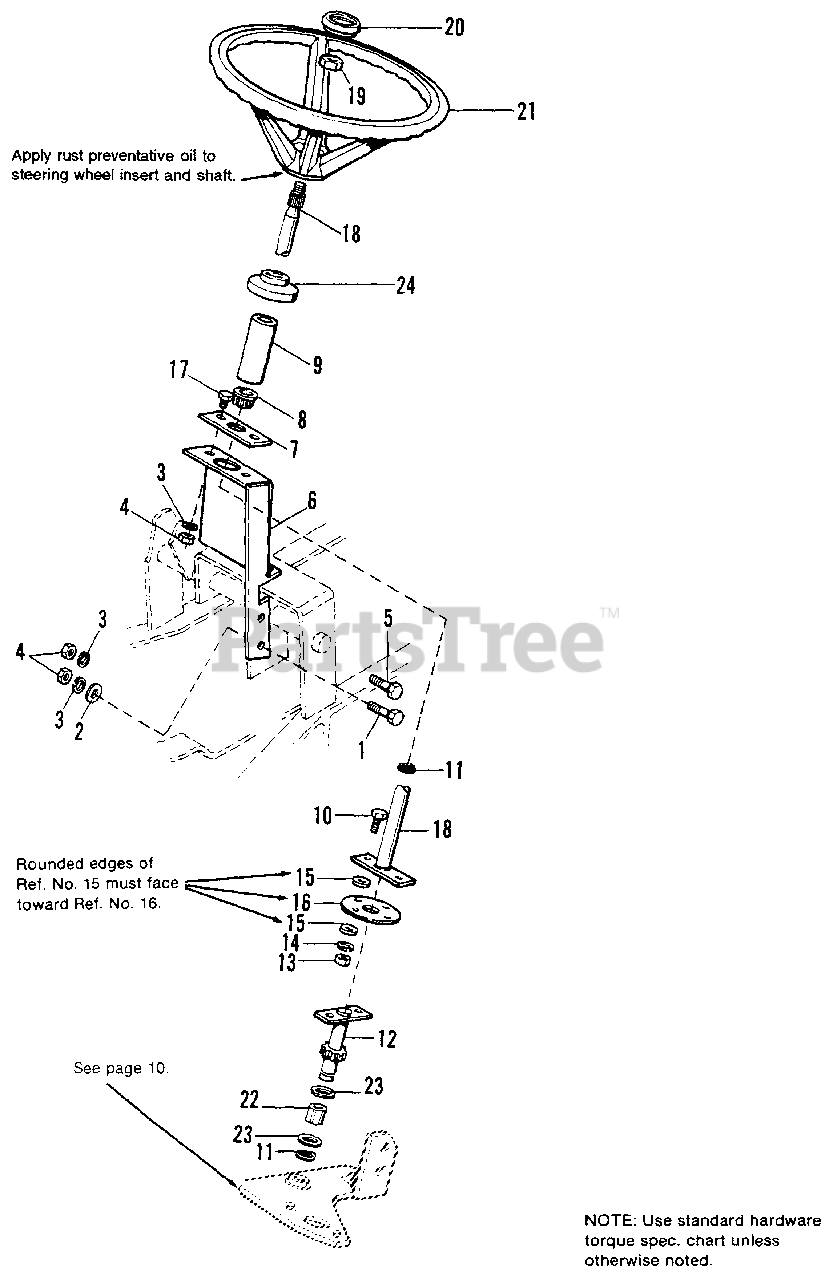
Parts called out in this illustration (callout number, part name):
1	CAPSCREW, Hex Hd., 3/8-16 x 1-1/4
2	WASHER, Plain, 5/16
3	LOCKWASHER, 3/8
4	NUT, Hex, 3/8-16
5	CAPSCREW, Hex Hd., 3/8-16 x 1
6	BRACKET ASSY., Steering
7	PLATE, Steering
8	BUSHING, Steering
9	TUBE, Steering Hub
10	CAPSCREW, Hex Hd., 3/8-16 x 3/4
11	RING, RETAINING, 3/8
12	SHAFT, Pinion & Coupling, Lower Steering
13	NUT, Hex, 5/16-18
14	LOCKWASHER, 5/16
15	WASHER, Plain, 5/16
17	CAPSCREW, Hex Hd., 5/16-18 x 1
18	SHAFT & COUPLING ASSY.
19	NUT, Hex, Jam, 5/8-18
20	CAP, Steering Wheel
21	WHEEL ASSY., Steering
23	WASHER, Thrust, 49/64 x 1-3/8 x 1/16
24	BOOT, Steering Stem
